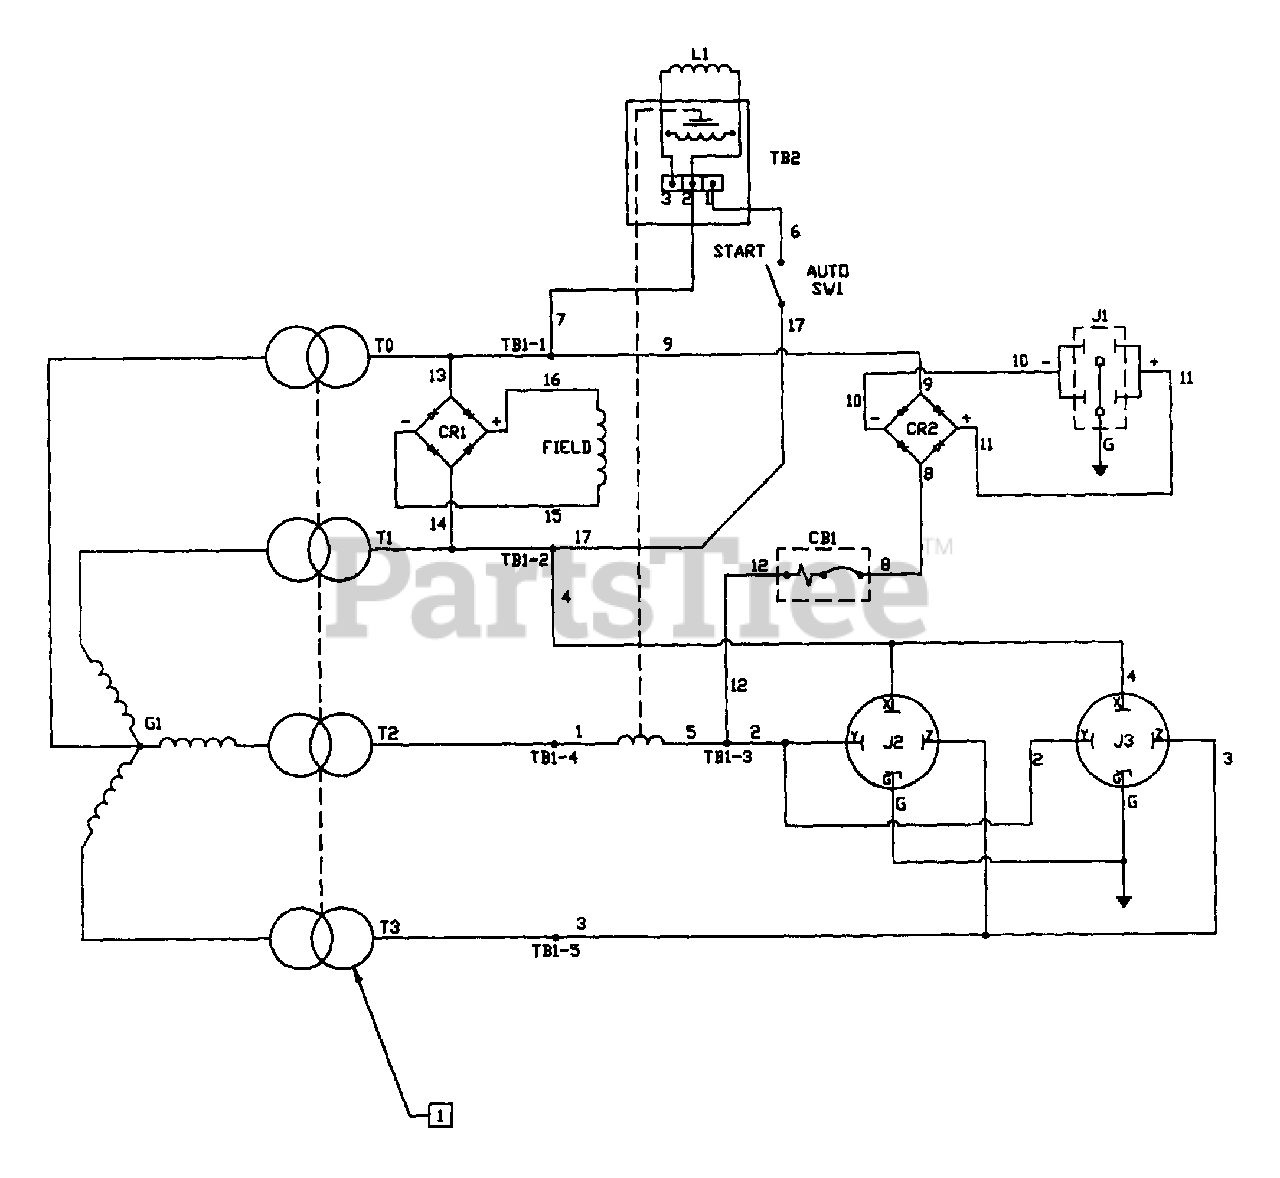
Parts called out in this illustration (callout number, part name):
G1	3-PHASE 180 HZ 6 POLE STATIONARY FIELD GENERATOR
CB1	25 AMP A.C. CIRCUIT BREAKER
CR1	FULL WAVE BRIDGE RECTIFIER - 35 AMP
J1	120 VOLT, DUPLEX RECEPTACLES
J2	230 VOLT, 3 POLE, 4 WIRE GROUNDING RECEPTACLE
J3	230 VOLT, 3 POLE, 4 WIRE GROUNDING RECEPTACLE
L1	IDLE CONTROL SOLENOID
TB1	5 PLACE 30 AMP TERMINAL BOARD
SW1	SPST SWITCH
TB2	IDLE CONTROL BOARD
CR2	FULL WAVE BRIDGE RECTIFIER - 40 AMP
